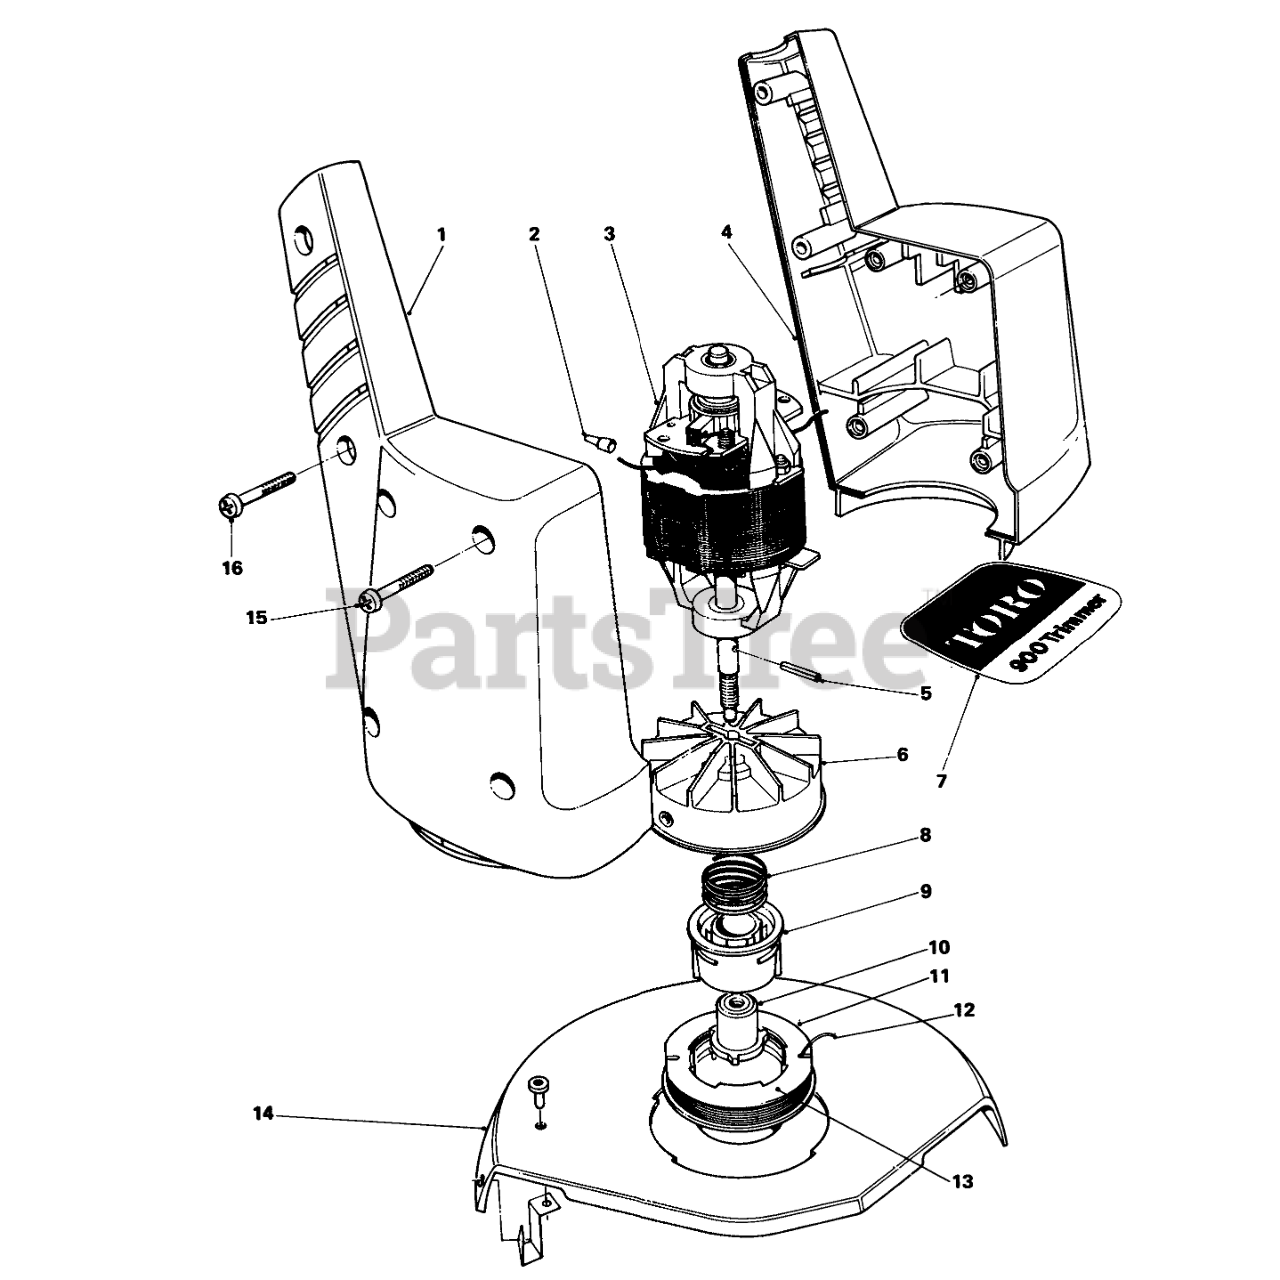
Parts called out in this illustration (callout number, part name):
1	Right Motor Housing
2	Wire Connector
3	Motor
4	Left Motor Housing
5	COIL PIN
6	Fan Hub with Eyelet
7	Toro 900 Decal
8	SPRING-COMPRESSION
9	CORE - SPOOL
10	Driver
11	SPOOL CAP
12	.040" Cutting Line in Coil
13	Prewound Spool
14	Shield with Cut-off Blade
15	SCREW-PPH
